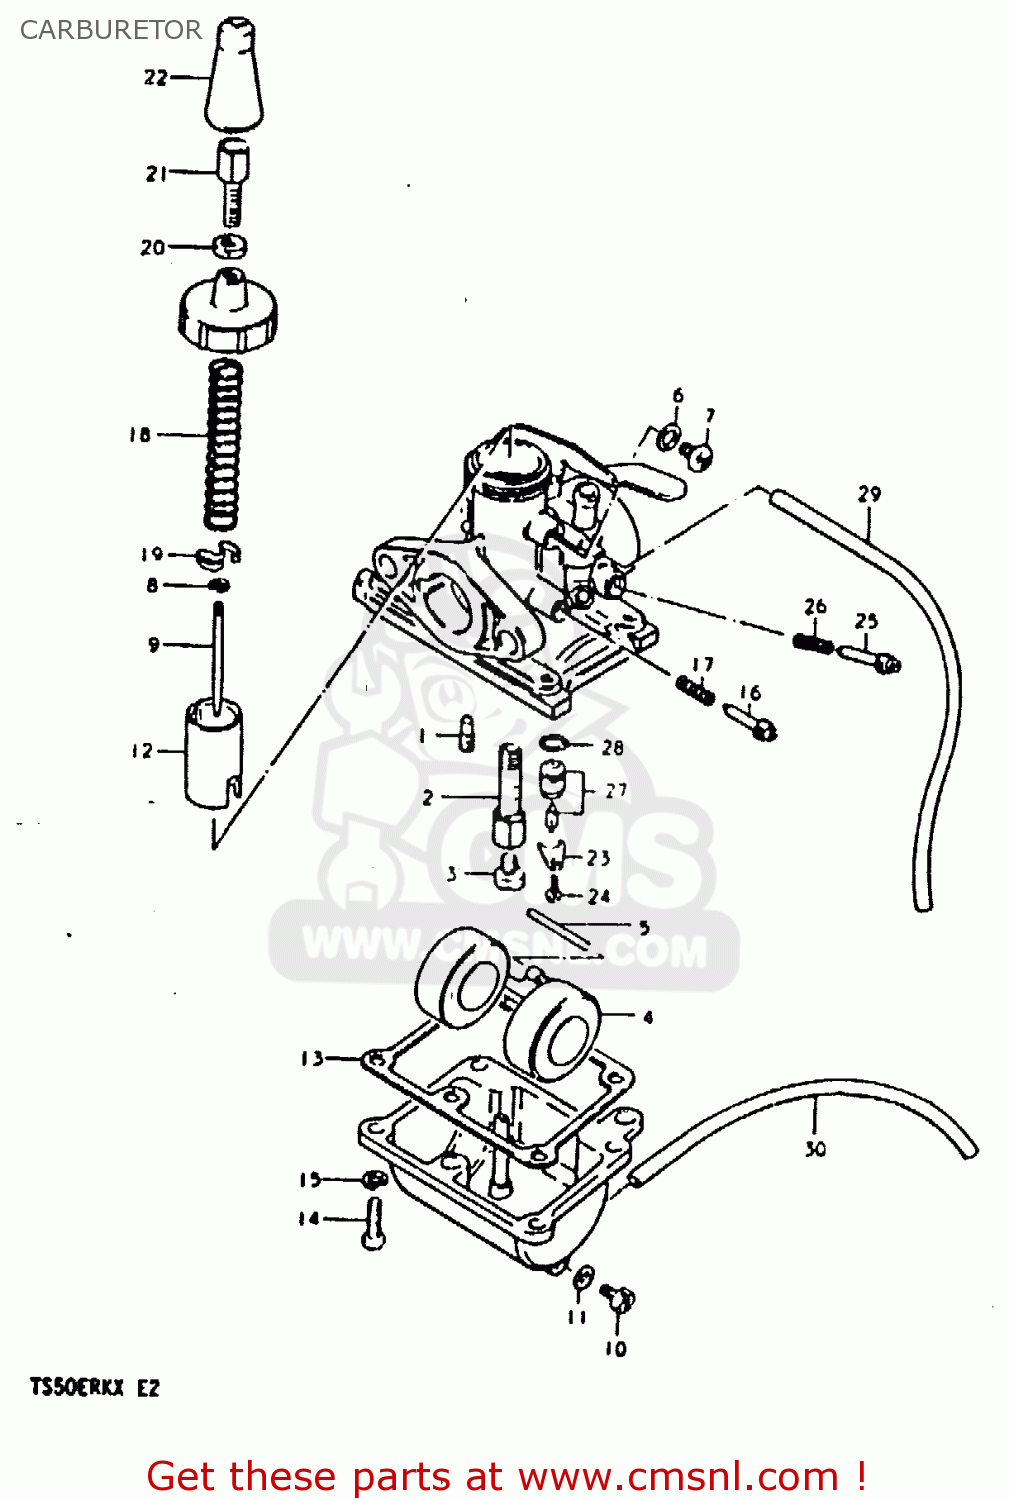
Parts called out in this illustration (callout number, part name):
1	JET,PILOT
2	JET, NEEDLE (E-7)
3	JET,MAIN(70)
4	FLOAT
5	PIN,FLOAT
6	RING
7	SCREW
8	CLIP,NEEDLE
9	NEEDLE,JET
10	PLUG
11	GASKET,DRAIN,PLUG (NAS)
12	VALVE,THROTTLE(CA:2.0)
13	GASKET,FLOAT CHAMBER (NAS)
14	SCREW
15	LOCK WASHER
16	SCREW,THROTTLE STOP
17	SPRING
18	SPRING,THROTTLE VALVE RETURN
19	PLATE,THROTTLE VALVE
20	NUT
21	ADJUSTER,CABLE
22	CAP
23	PLATE,NEEDLE VALVE FITING
24	SCREW
25	SCREW,AIR
26	SPRING
27	VALVE ASSY,NEEDLE
28	O-RING,NEEDLE VALVE
29	HOSE
30	HOSE
